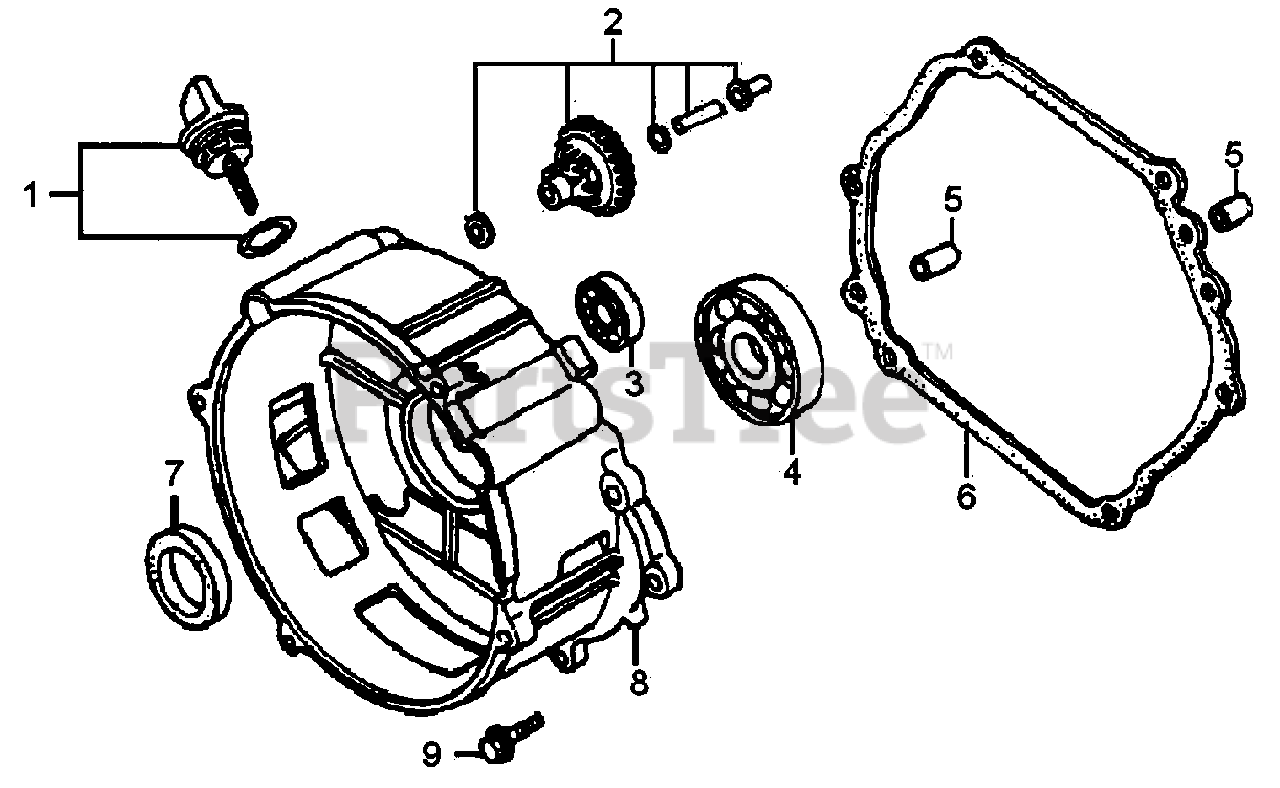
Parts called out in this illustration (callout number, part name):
1	CAP ASSY
2	GOVERNOR ASSY.
3	BEARING, RADIAL BALL 6202
4	BEARING, RADIAL BALL 6207
5	DOWEL PIN 8×12
6	GASKET, CRANKCASE COVER
8	CRANKCASE COVER
9	BOLT, FLANGE 8X40
